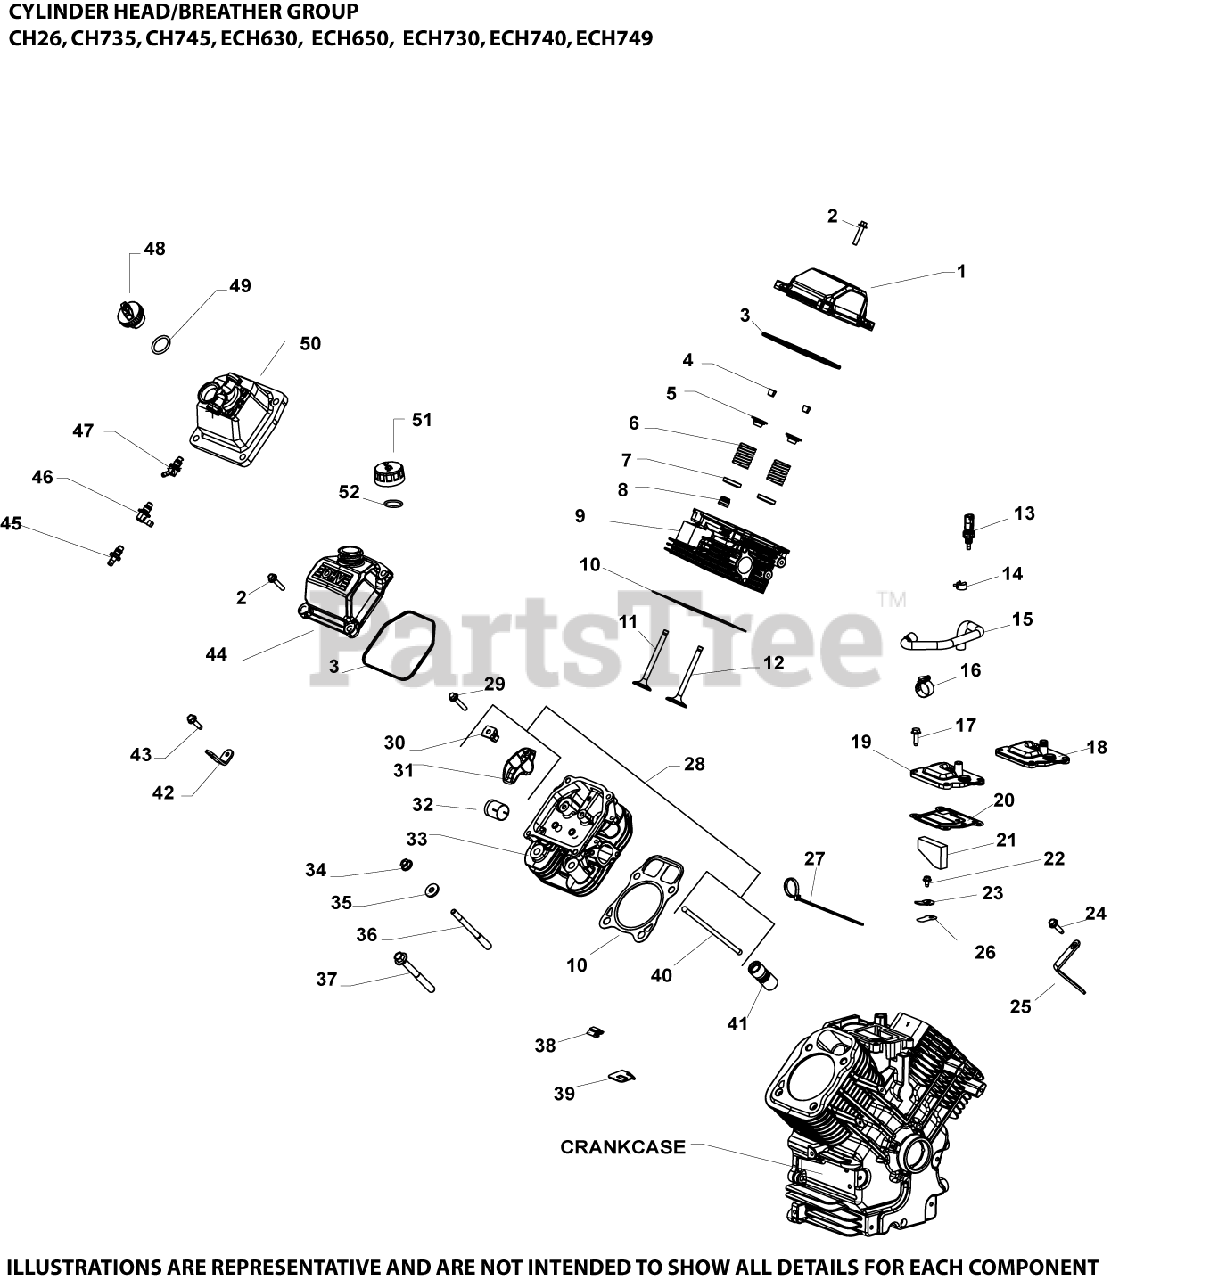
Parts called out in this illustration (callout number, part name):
1	KIT, VALVE COVER-PLAIN
2	SCREW, FLG M6X1.0X30
3	O-RING (YELLOW), VALVE COVER
4	KIT, RETAINER
5	CAP, VALVE SPRING
6	SPRING, VALVE
7	RETAINER, SPRING
8	SEAL, VALVE STEM - (#2503214S)
9	KIT, CYLINDER HEAD #1 USE 24 318 155-S
10	KIT, CYLINDER HEAD GASKET
11	VALVE, EXHAUST (STD) - USE 32 016 01-S
11	VALVE, EXHAUST (.25)
12	VALVE, INTAKE (STD)
12	VALVE, INTAKE (.25)
13	SENSOR, TEMPERATURE
14	CLAMP, BAND SPRING HOSE-(#2523737S)
15	HOSE, BREATHER - EFI HORIZONTAL
16	CLAMP, HOSE-USE 25 237 32-S
17	SCREW, THREAD FORMING
18	KIT, BREATHER COVER USE 24 096 165-S
20	GASKET, BREATHER
21	FILTER, BREATHER
22	SCREW, FLG THD FRM M5X.8X10
23	RETAINER, REED
25	STRAP, LIFT
26	REED, BREATHER
28	KIT, VALVE TRAIN
29	SCREW, FLG M6X1.0X34
30	PIVOT, ROCKER ARM
31	ARM, ROCKER
32	LINER, EXHAUST PORT
33	KIT, CYLINDER HEAD #2 USE 24 318 156-S
34	NUT, FLG M8X1.25
35	WASHER, FLAT 8.6 MM
36	STUD, M8X1.25
38	CLIP, O2 SENSOR
39	BRACKET, OXYGEN SENSOR
40	ROD, PUSH
41	LIFTER, VALVE HYDRAULIC - (#2535111S)
42	STRAP, BREATHER - USE 24 755 241-S
43	SCREW, THREAD FORMING
46	KIT, 90 DEG. FITTING
48	CAP ASSY, OIL FILL (YELLOW)
50	KIT, VALVE COVER-FUEL PUMP
52	O-RING, DIPSTICK
